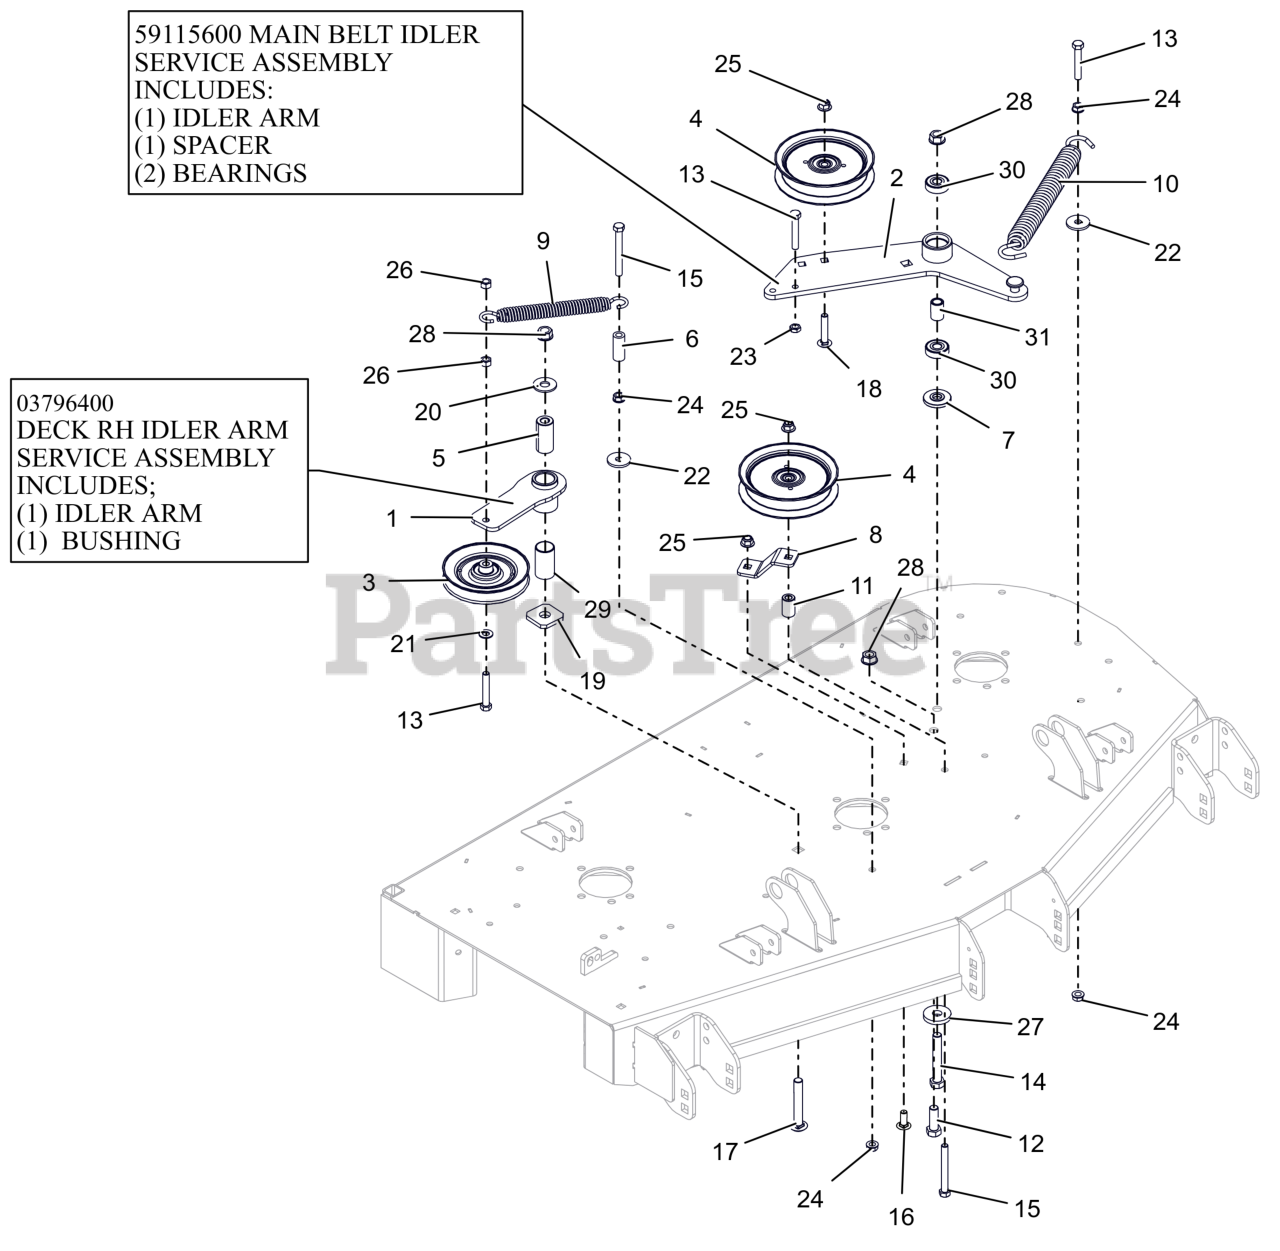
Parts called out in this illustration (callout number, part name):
1	WMT, IDLER ARM - BLACK
1	ASM, IDLER ARM (DECK)
2	WLDMT, DECK PTO IDLR ARM
2	ASSEMBLY, MAIN BELT IDLER
3	IDLER, V-5.00"
4	IDLER, FLAT 5.00"
5	BSHG, SPCR .502X.997X2.03 PM
6	HOSE, .38 X 1.65
7	SPACER, IDLER ARM
8	PTO FIXED IDLER MTG BRKT-ORG
9	SPRING, EXTENSION
10	SPRING, EXTENSION
11	BUSHING, SLV .380X.750X1.190
12	BLT,HEX .50-13X1.50 G5 ZCC
13	BLT,HEX .38-16X2.25 G5 ZCC
14	BLT,HEX .50-13X3.25 G5 ZCC
15	BLT, HEX .38-16X3.25 G5 ZCC
16	BLT,RHSSN .38-16X1.00 G5 ZCC
17	BTL,RHSSN .500-13 X 3.25 G5 ZCC
18	BLT,RHSSN.375-16X2.00 G5 ZCC
19	WSHR-FLT .640X1.75X.250
20	WSHR,FLT .563X1.375X.109 ZCC
21	WSHR,FLT .406X.812X.065 ZCC
22	WSHR,FLT .406X1.375X.135 ZCC
23	NUT-JAM .375-16 G2 ZCC
24	NUT, SPNLK-FLG .38-16 G5 ZCC
25	NUT,NYL-FLG .38-16 GF ZCC
26	NUT-LK-CTR .38-16 ZC120
27	WSHR-FL-STL 0.557X1.625X0.25 ZCC
28	NUT-LK-CTR-FLG .500-13 GG ZCC
29	BSHG, 1.00X1.125X1.937
30	BRG-BALL .500X1.38X.437
31	SPACER .510 X .75 X 1.1485
